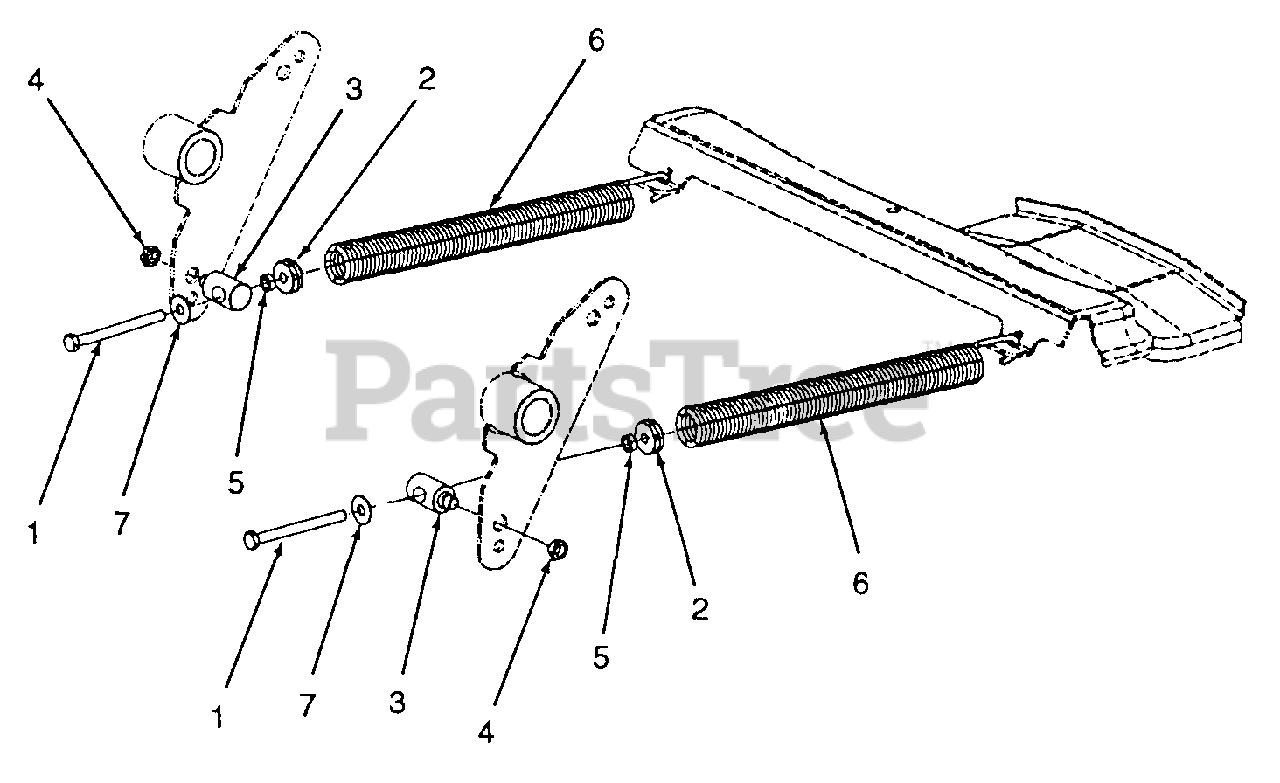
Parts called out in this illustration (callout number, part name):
1	Screw, Hex Cap, Special 5/16-18 x 3.5 GR5
2	Insert, Spring, 5/16-18 Thrd
3	Ferrule, .88 O.D. w/.160 Dia. Shldr
4	Nut, Hex Center Lock Jam, 3/8-24
5	Nut, Hex Jam, 5/16-18 GR5
6	Spring, Extension, 1.25 O.D. x 11.5
7	Washer, Flat, .349 x .879 x .063
